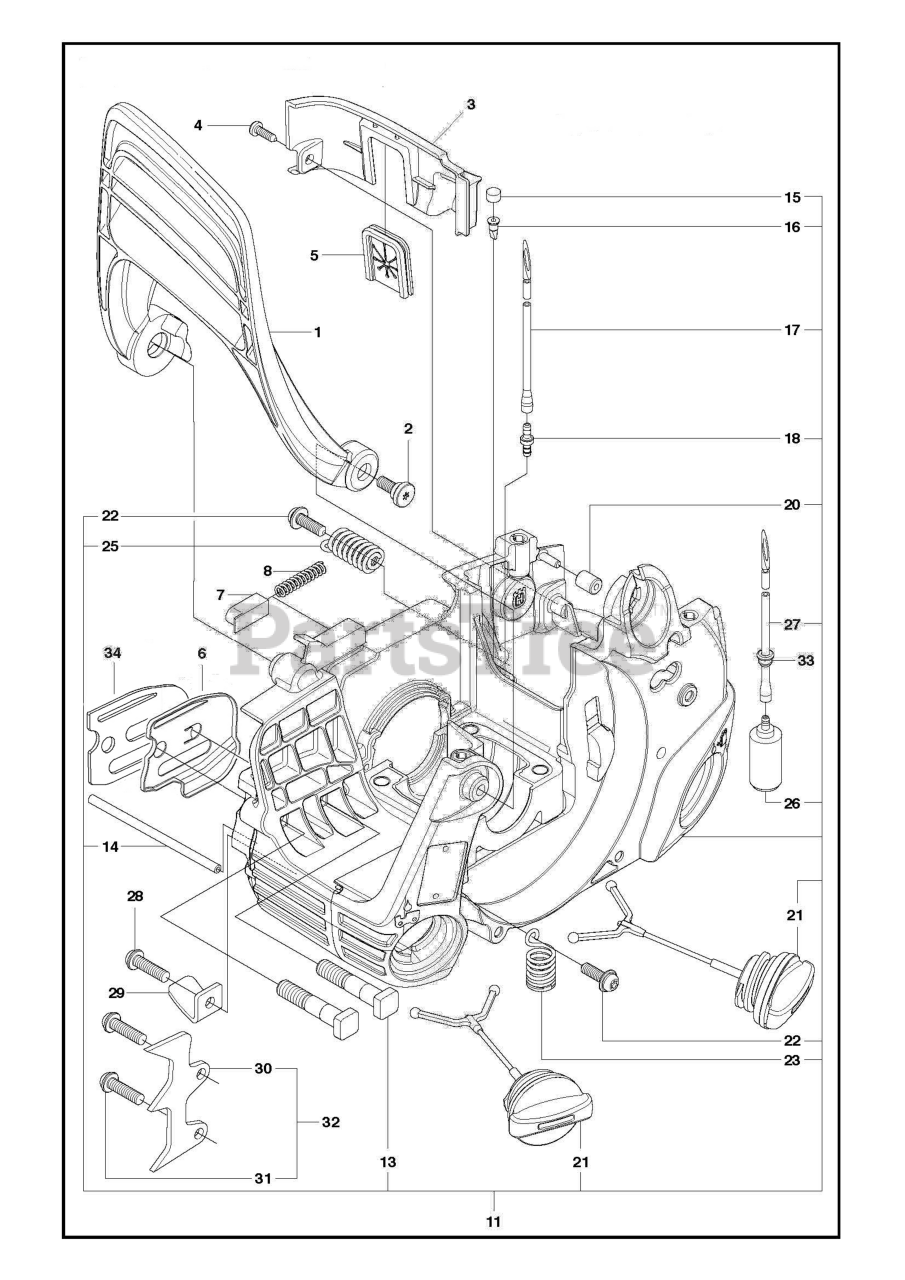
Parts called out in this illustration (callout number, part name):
1	HAND GUARD
1	HANDGUARD HHS
2	BOSS SCREW
4	SCREW 6-19X.437
7	CAP, SPRING HANDGUARD
11	ASSY CHASSIS HUSQ ORANGE
13	BAR BOLT 36/41
13	BOLT
15	VENT,FUEL TANK 36/41
16	VALVE-CHECK (DUCKBILL)
17	KIT.LINE TANK/PURGE
17	KIT FUEL LINE
18	FUEL LINE FITTING
20	ISOLATOR FILTER HOUSING
21	FUEL CAP W/ RETAINER
21	ASSY TANK CAP GREY
22	SCREW,FRONT HBAR 36/41
25	SPRING
25	SPRING REAR HANDLE ISOLATOR 96
26	FUEL PICK-UP ASSY
26	ASSY FUEL PICKUP PRE FLUSHED
27	FUEL LINE
27	KIT FUEL LINE
27	LINE FUEL LOW PERM
29	CHAIN CATCHER 36/41
30	SPIKE
32	SPIKE 36/41
33	FUEL TANK BUSHING
34	Spacers
